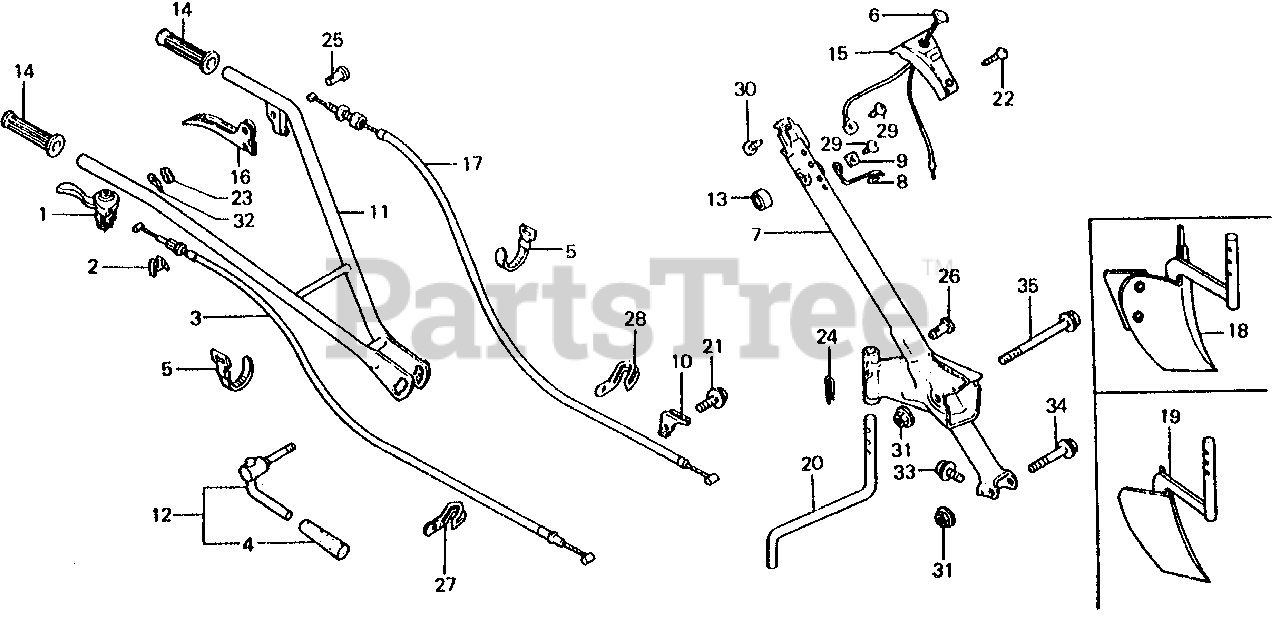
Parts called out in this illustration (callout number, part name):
1	LEVER ASSY., THROTTLE
3	CABLE, THROTTLE
4	GRIP, LEVER
5	BAND B1, CABLE
6	SWITCH, ENGINE STOP
7	HOLDER, COLUMN
7	HOLDER, COLUMN *NH35M* (CLOUD SILVER METALLIC)
8	GUIDE, CABLE
9	BRACKET, CABLE GUIDE
10	STOPPER, CABLE
12	LEVER, HANDLE ADJUSTING
13	STOPPER, ADJUSTING
14	GRIP, L. HANDLE
15	COVER, HANDLE
15	COVER, HANDLE *NH1* (BLACK)
16	LEVER, CLUTCH
17	CABLE, MAIN CLUTCH
18	RIDGER ASSY., WIDE
21	BOLT, FLANGE (6X12) (CT200)
22	SCREW, TAPPING (5X25)
23	WASHER, WAVE (10MM)
24	PIN, SNAP (7MM)
25	PIN (8X18)
26	PIN (7X48)
27	CLIP, TANK STAY
28	CLIP, HEAD
29	SCREW, TAPPING (5X10)
30	SCREW, TAPPING (5X16)
31	NUT, FLANGE (8MM)
32	PIN, LOCK (8MM)
33	BOLT, FLANGE (8X16)
34	BOLT, FLANGE (8X55)
35	BOLT, FLANGE (8X80)
